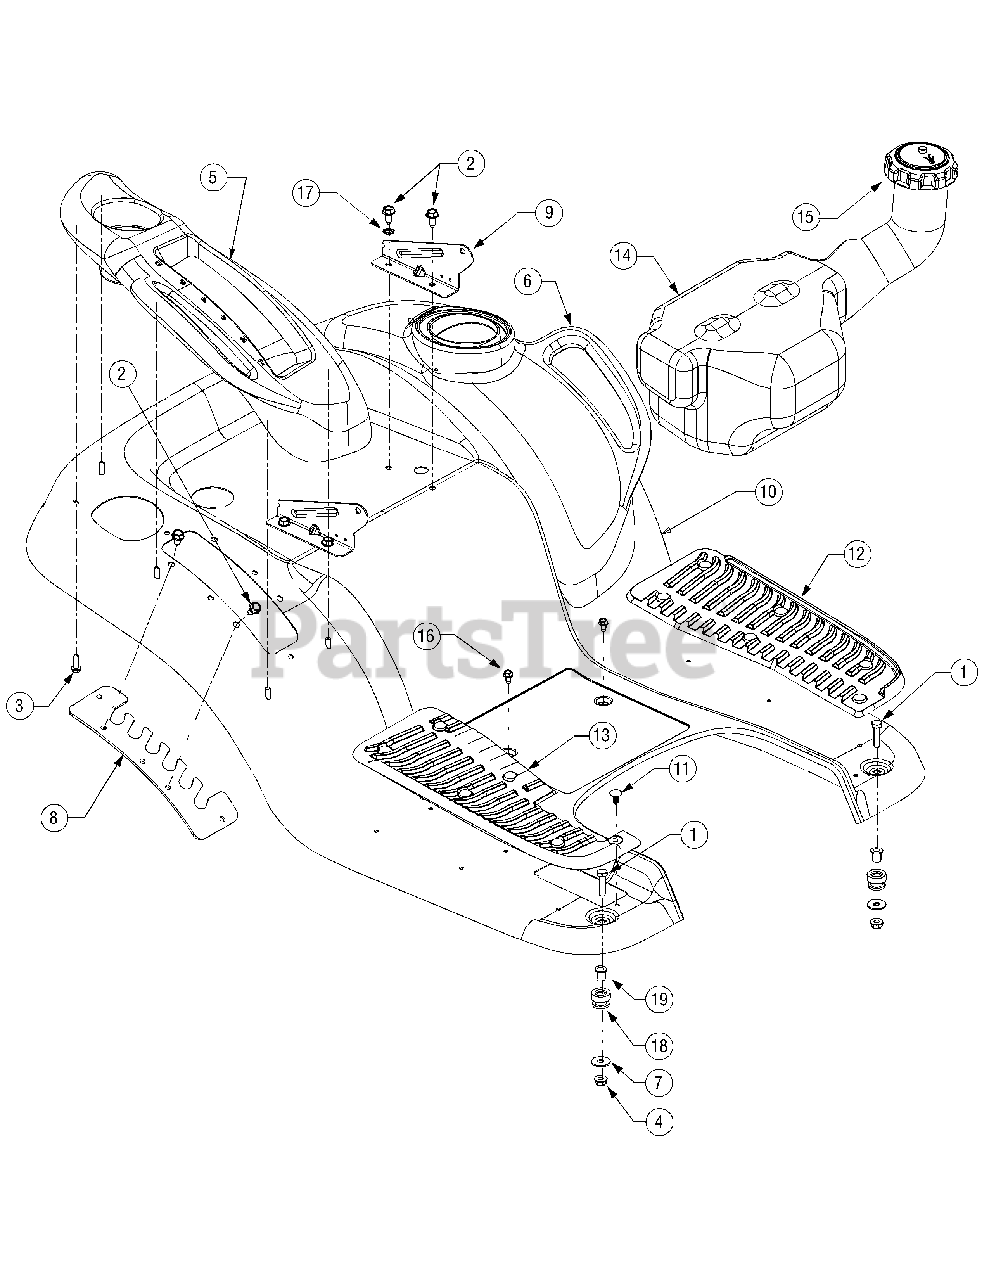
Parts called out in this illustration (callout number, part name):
1	Screw, 5/16-18 x 1.25
2	Screw, 5/16-12, 0.75
3	Screw, 1/4-15, 0.750
4	Nut, Nylon Lock, 5/16-18
5	Cover, Fender, RH
6	Cover, Fender, LH
7	Washer, Flat, .349 x 1.00 x .063
12	Pad, Foot, LH
13	Pad, Foot, RH
14	Tank, Fuel
15	Cap, Fuel
16	Screw, Self-tapping, 1/4-20, 0.500
17	Washer, Lock, 5/16 External Tooth
19	Flange Spacer, .3125 x .4375 x .625
